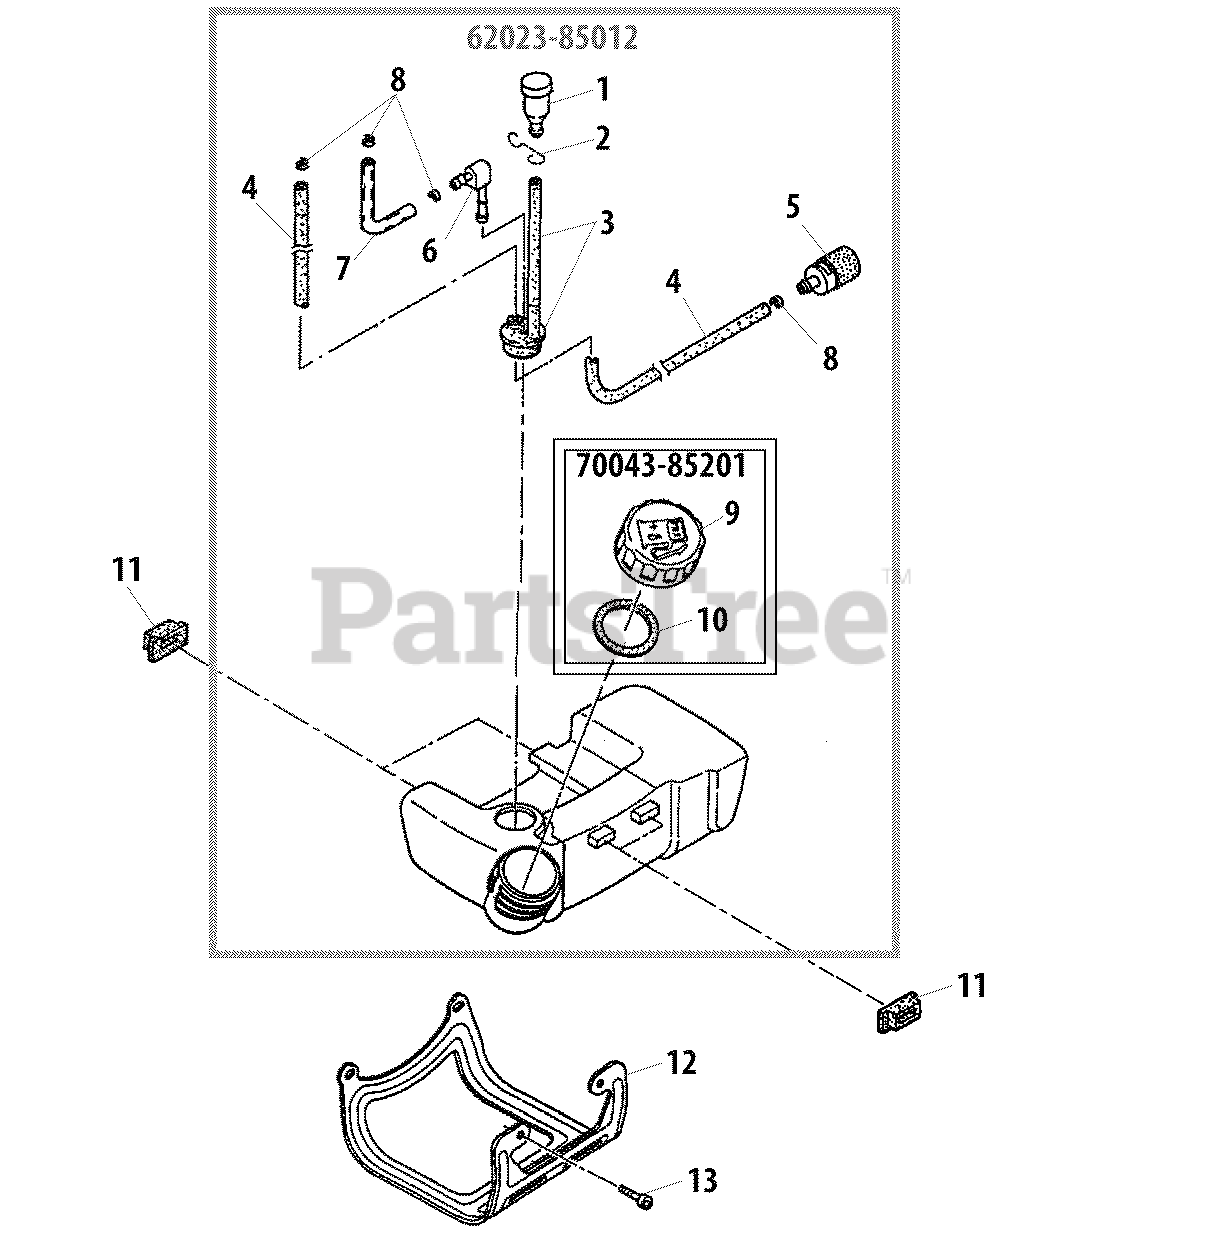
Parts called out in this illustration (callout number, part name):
1	VENT, FUEL TANK
2	HOLDER, VENT
3	VENT PIPE ASSY
4	PIPE - FUEL
5	FILTER, FUEL
6	CONNECTOR, PIPE
7	PIPE - RETURN
8	RING, RETAINING - 6
9	CAP, FUEL
10	GASKET, CAP
11	CUSHION, TANK
12	GUARD, FUEL TANK
13	SCREW - 5X12
62023-85012	FUEL TANK ASSY
70043-85201	CAP ASSY
